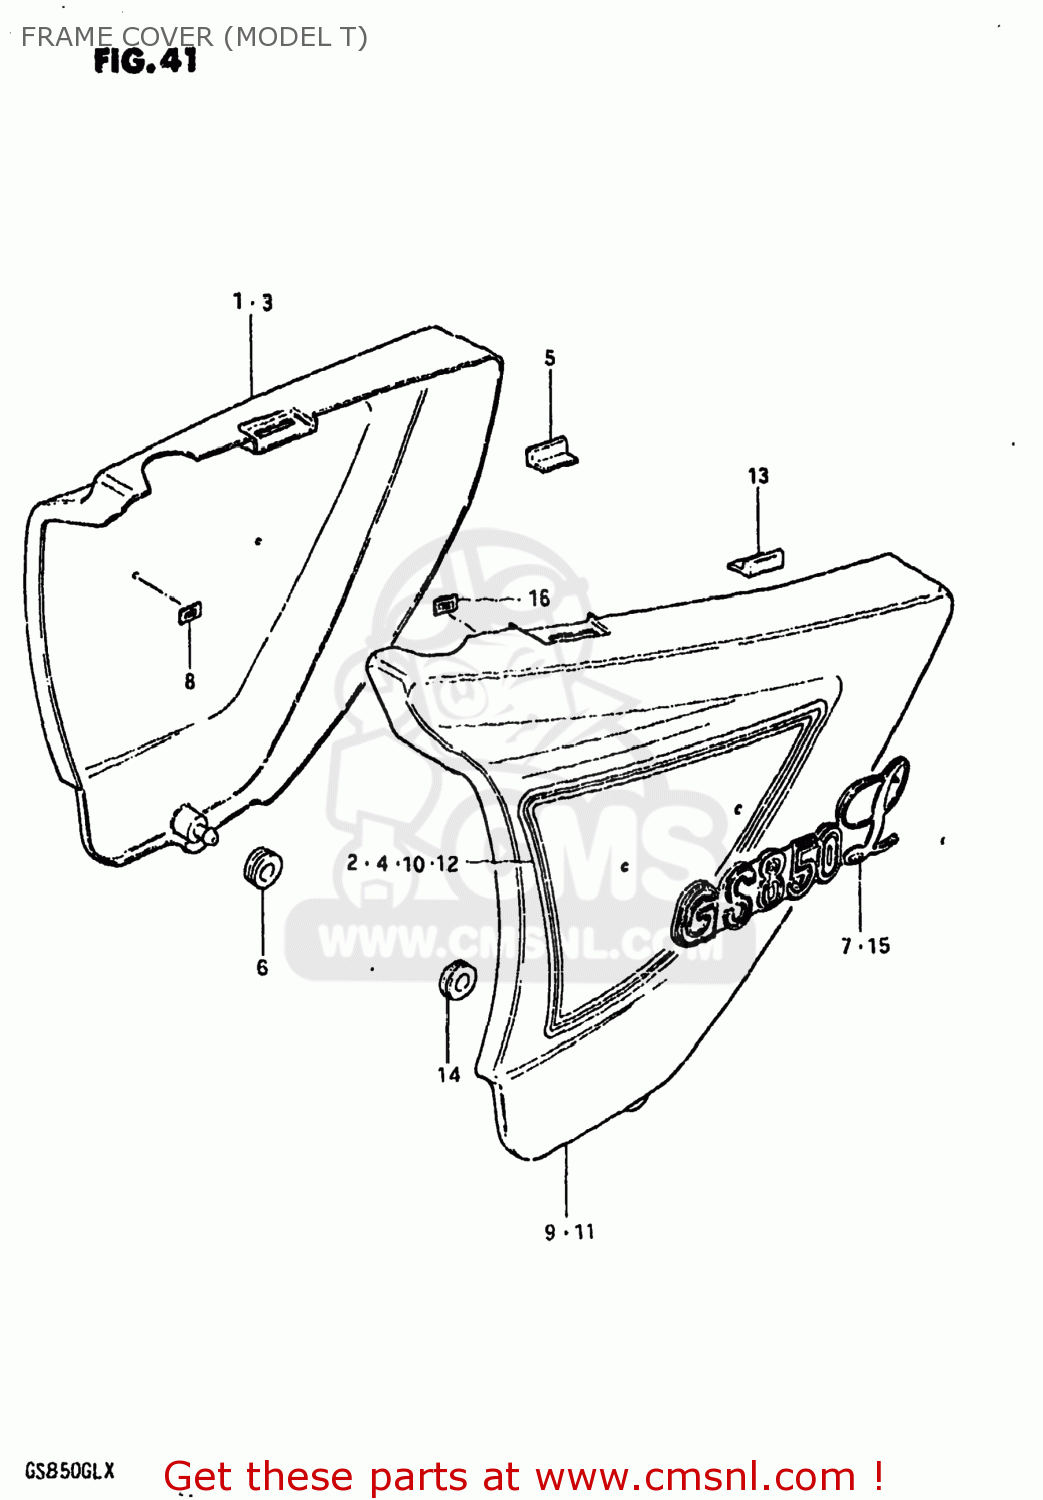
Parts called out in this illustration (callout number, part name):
1	COVER,FRAME,RIGHT
2	TAPE SET,FRAME COVER
3	COVER,FRAME,RIGHT
4	TAPE SET,FRAME COVER
5	CUSHION,FRAME COVER
6	CUSHION
7	EMBLEM
8	NUT
9	COVER,FRAME,LEFT
10	TAPE SET,FRAME COVER
11	COVER,FRAME,LEFT
12	TAPE SET,FRAME COVER
13	CUSHION,FRAME COVER
14	CUSHION
15	EMBLEM
16	NUT
